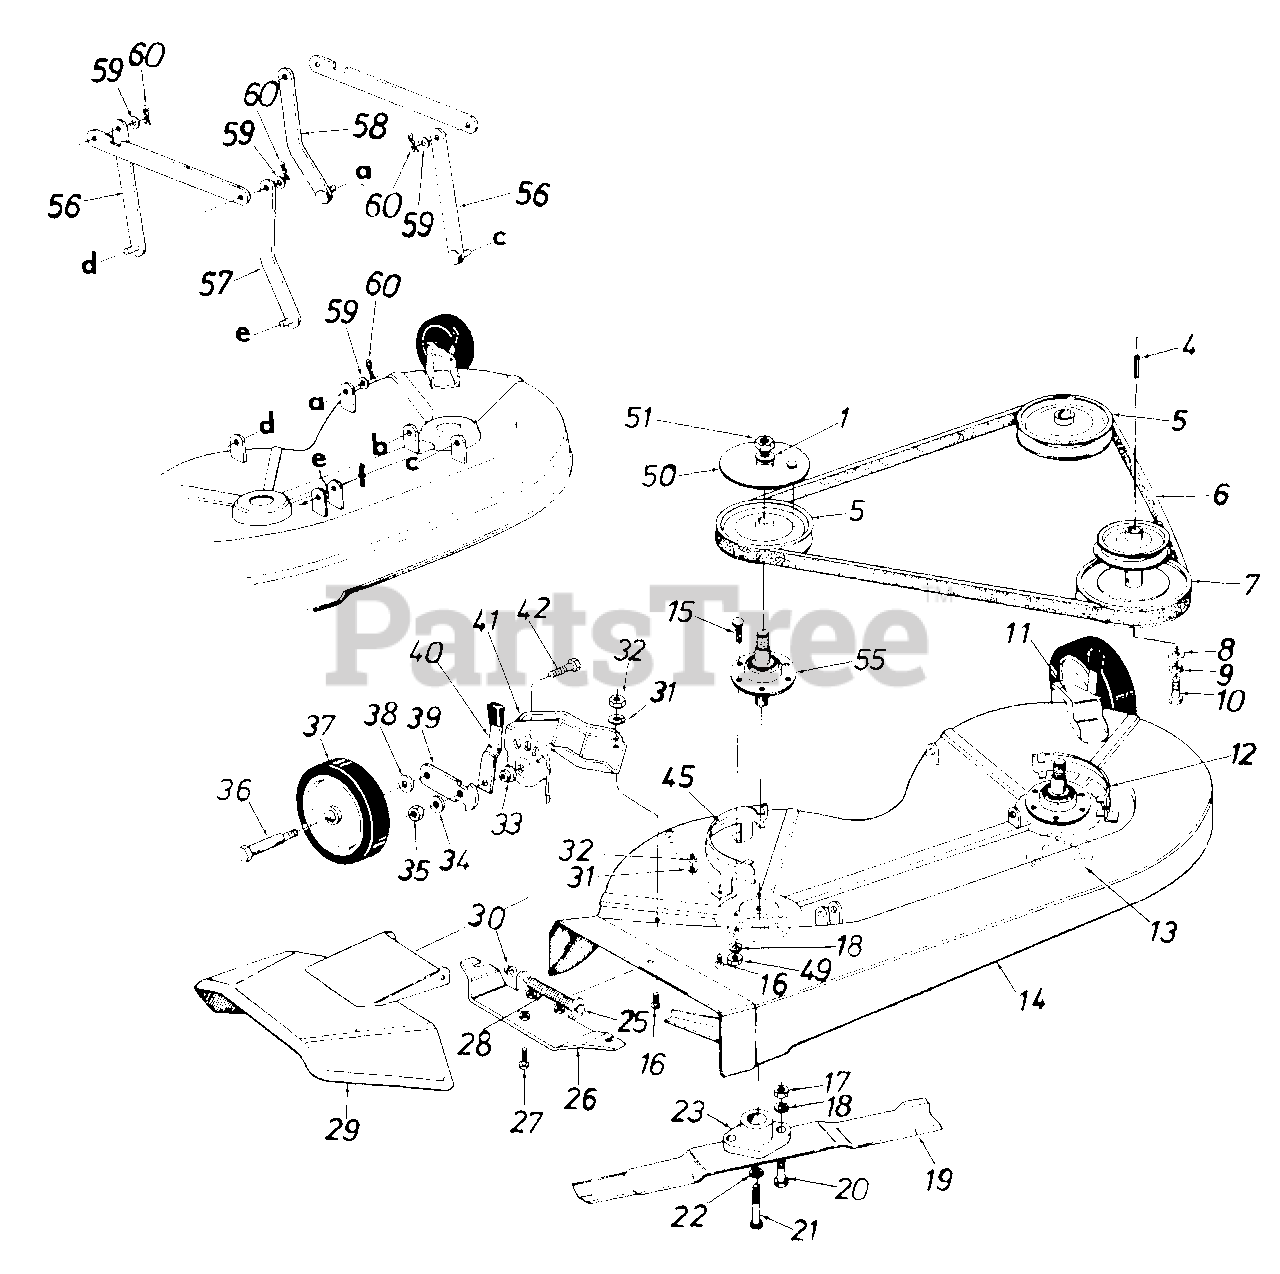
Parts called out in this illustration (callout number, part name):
1	L-Wash. 5/8" I.D.
4	Sq. Key 1/4" x 1/4" x 2.0" Lg.
5	Pulley 4.75" O.D.
6	"V"-Belt
7	See Lawn Tractor Manual
8	Fl-Wash. 7/16" I.D. x 1.25 O.D. x .180t
9	L-Wash. 7/16" I.D.
10	Hex Bolt 7/16-20 x 1.50" Lg.
11	Wheel Brkt.-L.H.
14	34" Deck Ass'y.
15	Rib Neck Bolt 5/16-24 x .67" Lg.
16	Hex Bolt 1/4-28 x .50" Lg.
17	Hex Nut 5/16-24 Thd.
18	L-Wash. 5/16" I.D.
19	17" Blade
20	Hex Bolt 5/16-24 x 1.00" Lg.(Grade 5)
21	Hex Bolt 3/8-24 x 1.50" Lg.(Grade 5)
22	L-Wash. 3/8" I.D.
23	Blade Adapter Kit
25	Hinge Pin
26	Adapter Plate
27	Hex Wash. Self-Tap Scr. 1/4-20 x .50" Lg.
28	Torsion Spring
29	Chute Cover Ass'y.-Comp.
30	Push Nut 1/4" Rod
31	L-Wash. 1/4" I.D.
32	Hex Nut 1/4-28 Thd.
33	Shld. Spacer
34	Bell-Wash. .400" I.D. x 1.13"
35	Hex Top L-Nut 3/8-16 Thd.
36	Shld. Bolt .498" Dia. x 1.53"
37	Plastic Wheel 5.0" x 1.38"
38	Bell-Wash. .400" I.D. x .88"
39	Pivot Bar
40	Spring Lever Ass'y. w/Knob
41	Wheel Brkt.-R.H.
42	Hex Bolt 3/8-16 x 1.00" Lg.
45	Belt Guard-R.H.
49	Hex Nut 5/16-24 Thd.
50	Brake Disc
51	Hex Jam L-Nut 5/8-11 Thd.
55	Blade Spindle Ass'y. Comp.
56	Link Deck Hanger Ass'y.
57	Link Deck Hanger Ass'y.
60	Inter. Cotter Pin .50" Dia.
